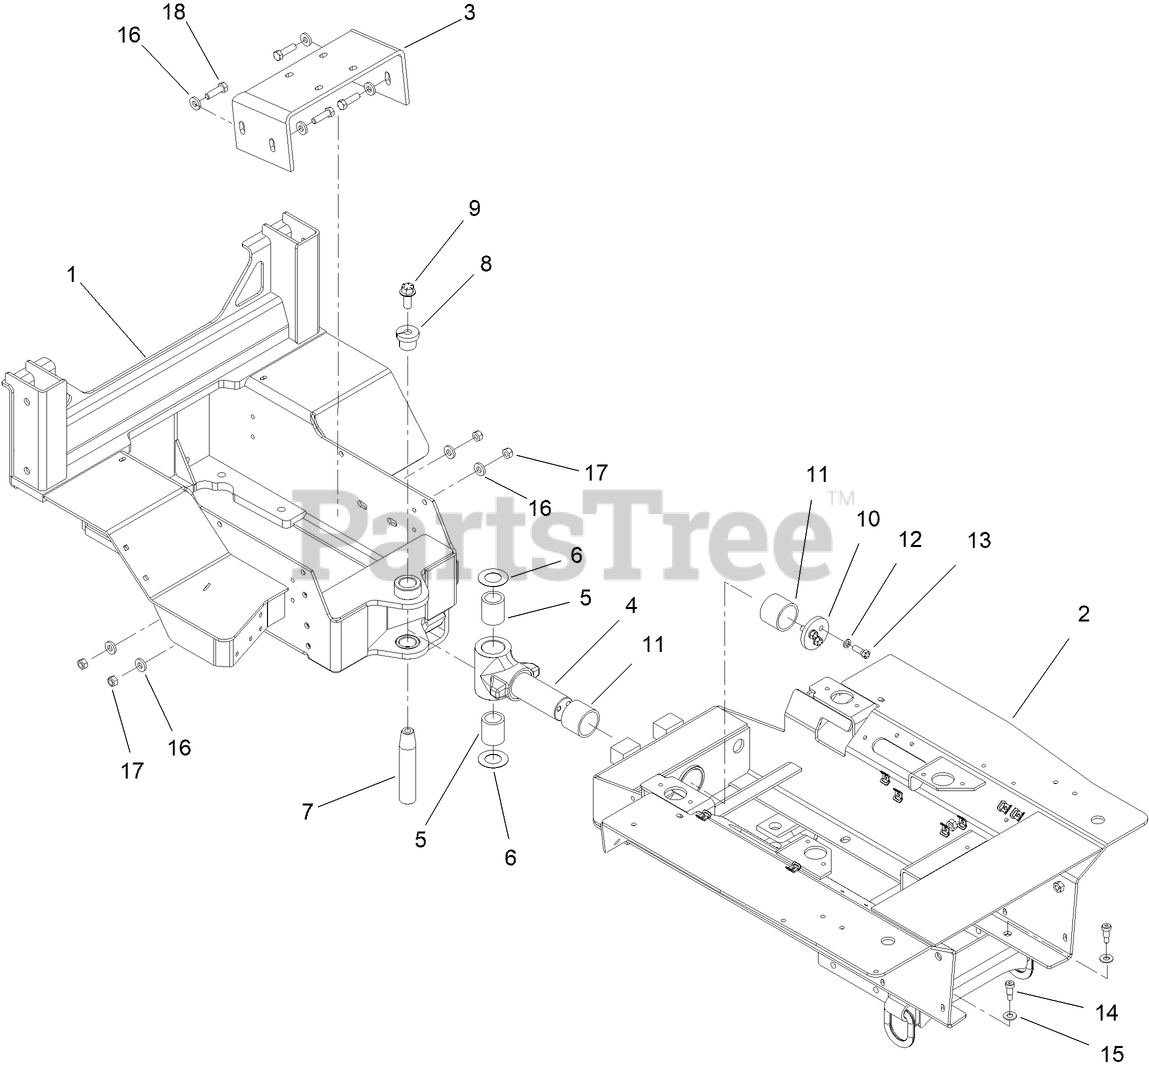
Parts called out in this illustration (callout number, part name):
1	REAR FRAME
2	FRAME-FRONT WELDED
3	MOUNT-GEARBOX
4	PIVOT-MACHINING
5	BEARING-COMPOSITE
6	WASHER - MACHINERY (1.375)
7	TAPERED PIN (1.375" X 7.000")
8	TAPERED INSERT (1.375")
9	FLG BLT (5/8-NC X 1-1/2", GR 8)
10	CAP-PIVOT
11	BEARING - COMPOSITE
12	WASHER-LOCK
13	SCREW-HH
14	SHOULDER BOLT
15	WASHER-FLAT
16	WASHER-HARDENED
17	LOCKNUT
18	SCREW-HH
